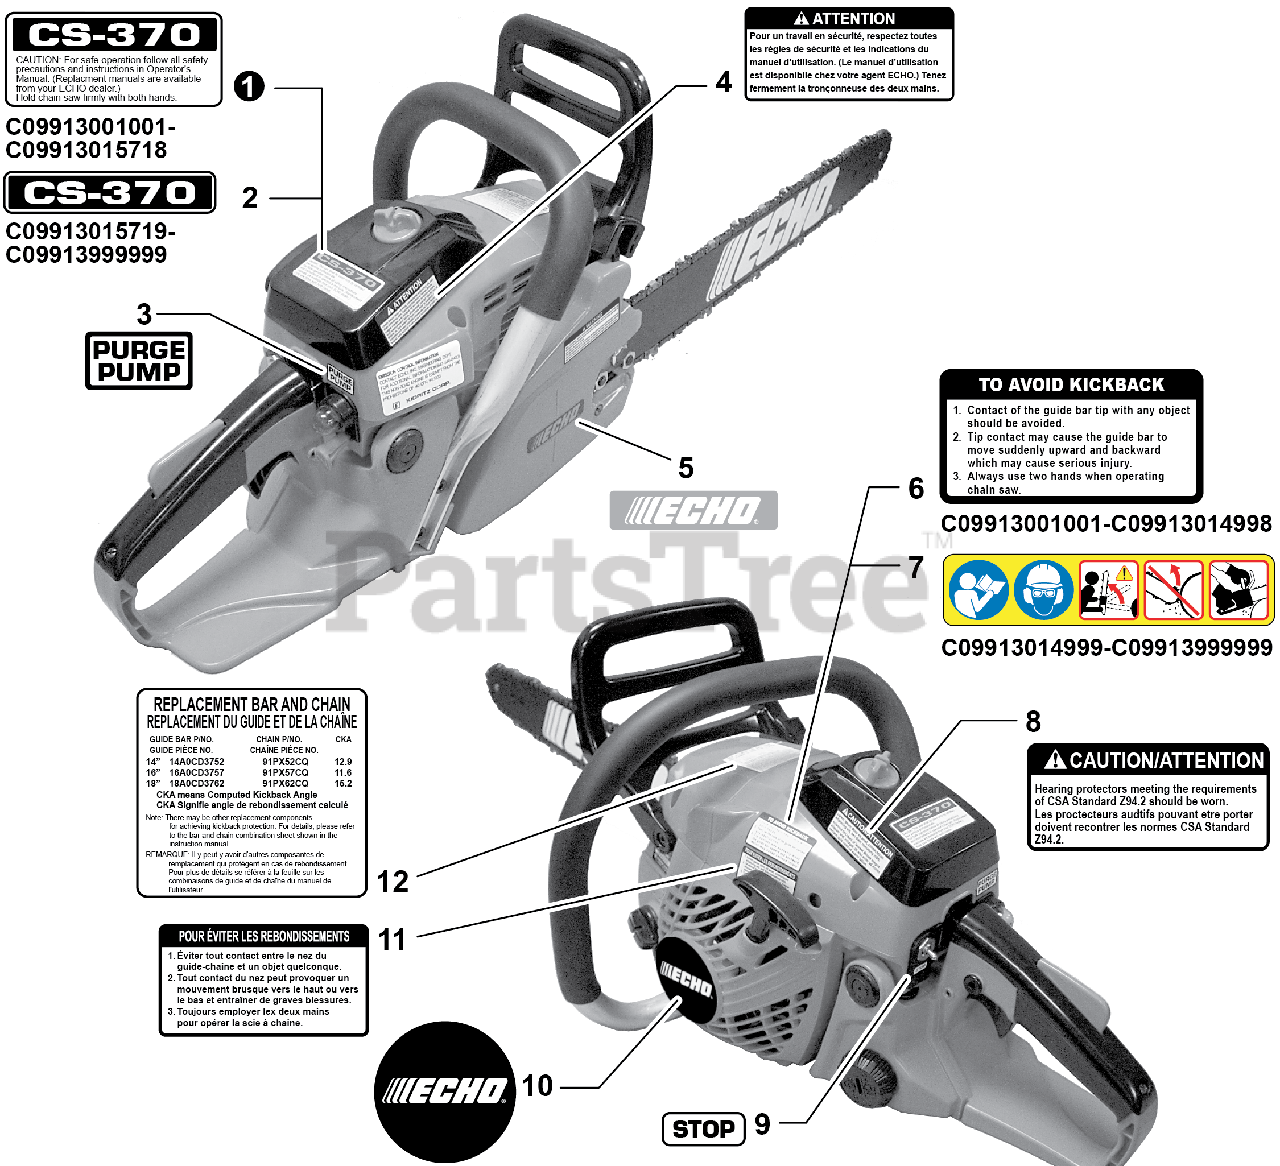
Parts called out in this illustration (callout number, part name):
1	LABEL - MODEL CS-370
2	LABEL - MODEL CS-370
3	LABEL, PURGE PUMP
4	LABEL, ATTENTION - CANADA
5	LABEL, ECHO
6	LABEL, KICK BACK
7	LABEL, CAUTION
8	LABEL, NOISE - ENGLISH/FRENCH
9	LABEL, STOP
10	LABEL, ECHO
11	LABEL, KICK BACK - FRENCH
12	LABEL, BAR & CHAIN - CANADA
